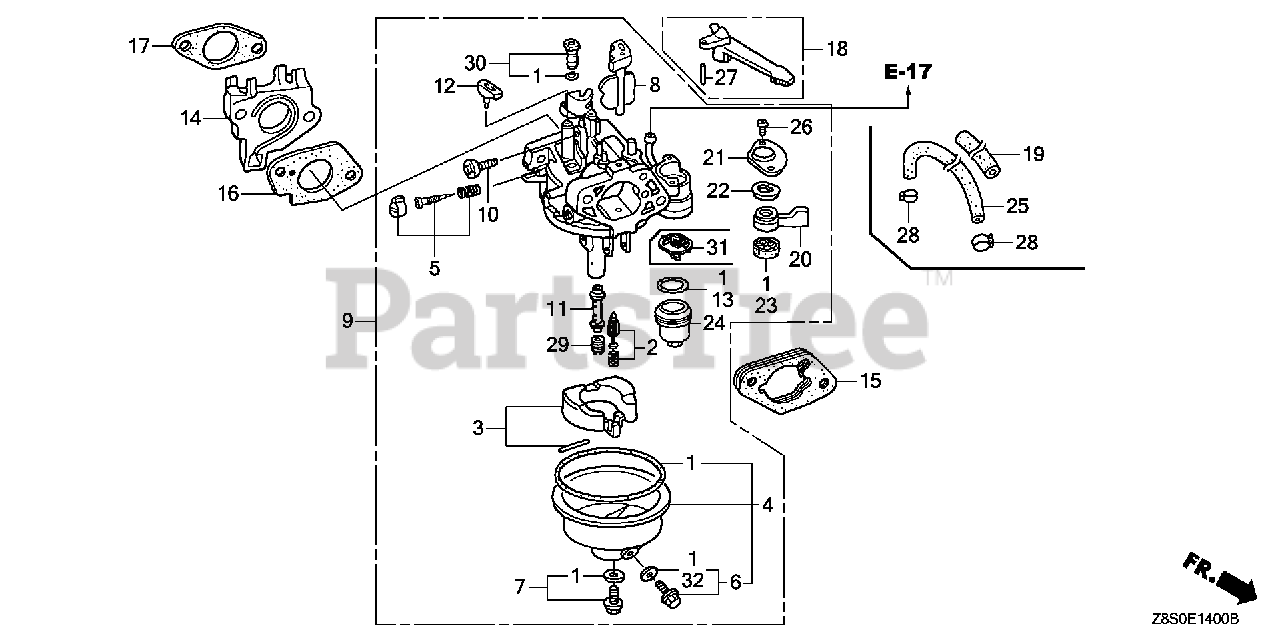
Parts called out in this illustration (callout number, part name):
1	GASKET SET (INCLUDES 16173-001-004)
2	VALVE SET, FLOAT
3	FLOAT SET (CARBURETOR NO.)
4	CHAMBER SET, FLOAT
5	SCREW SET, PILOT
6	SCREW SET, DRAIN
7	SCREW SET
9	CARBURETOR ASSY. (BE70N A)
10	SCREW, THROTTLE STOP
11	NOZZLE, MAIN
12	COLLAR, SETTING
13	GASKET, FUEL STRAINER CUP
14	INSULATOR, CARBURETOR
15	SPACER, CARBURETOR
16	GASKET, CARBURETOR
17	GASKET, INSULATOR
18	LEVER, CHOKE (STD)
20	LEVER, PETCOCK
21	PLATE, LEVER SETTING
22	SPRING, PETCOCK LEVER
23	GASKET, PETCOCK
24	CUP, FUEL STRAINER
26	SCREW, PAN (3X6)
27	PIN, SPRING (2X12)
29	JET, MAIN (#82)
29	JET, MAIN (#85)
29	JET, MAIN (#88)
30	JET SET, PILOT (#40) (CARBURETOR NO.)
